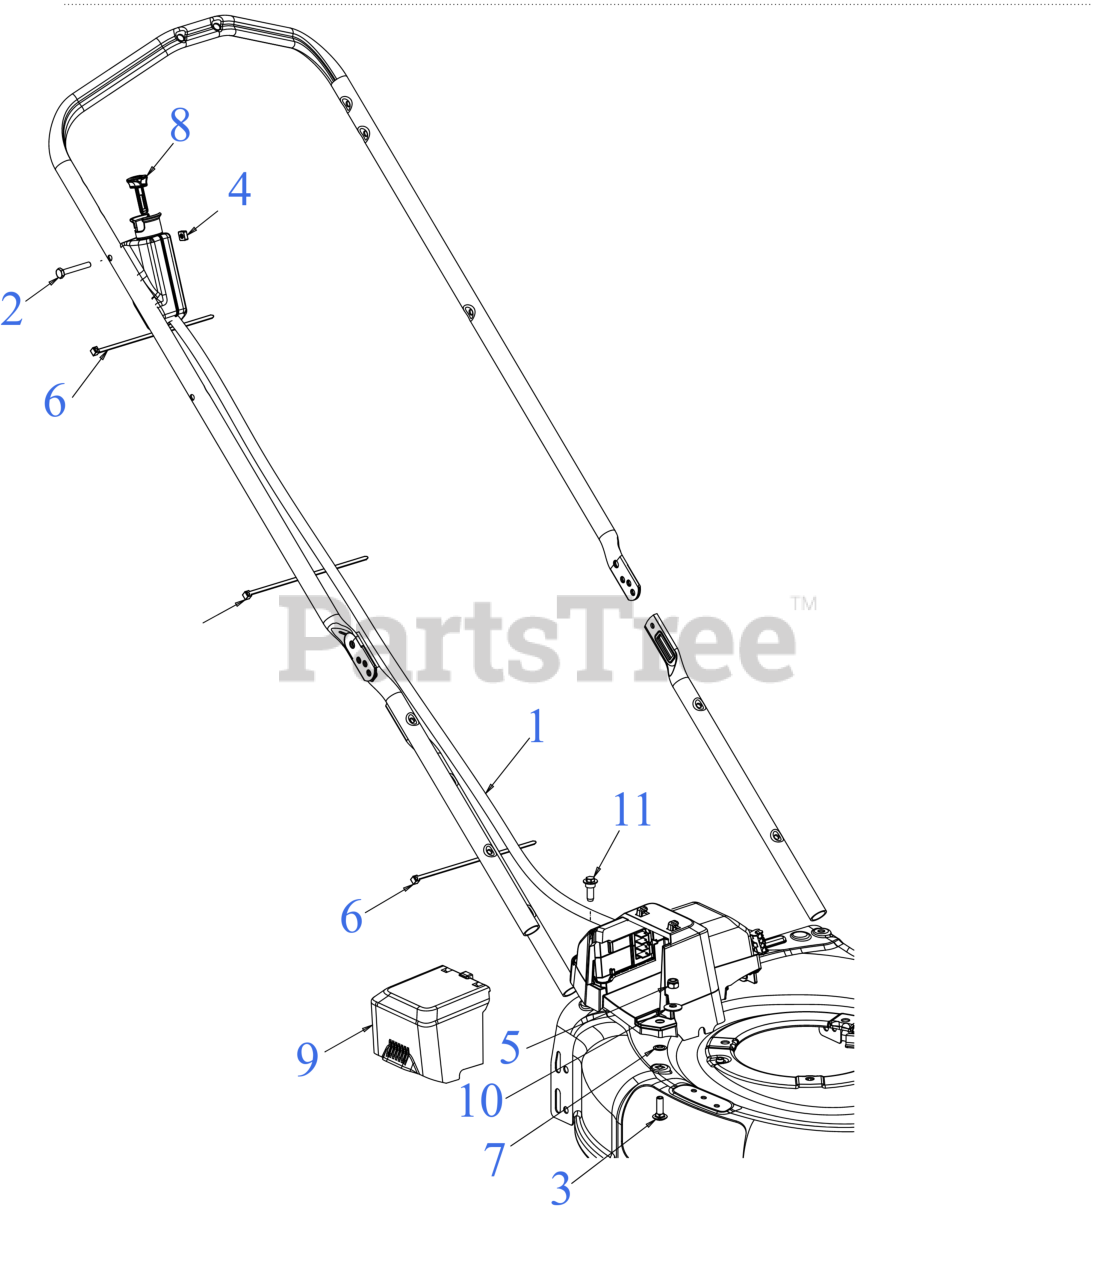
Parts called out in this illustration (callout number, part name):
1	HARN ASM:ESTART:BTN:LI-ION
2	HEX SCREW 1/4-20 x 1.75
3	CARRIAGE BOLT 5/16-18 x 1.00
4	SQUARE NUT 1/4-20
5	HEX NUT
6	7" CABLE TIE
7	PUSH NUT
8	PUSH KEY
9	BATTERY HOUSING (DOOR)
10	BELL WASHER .337 X.867 x .057
11	SHOULDER SCREW 5/16-14 x .972
